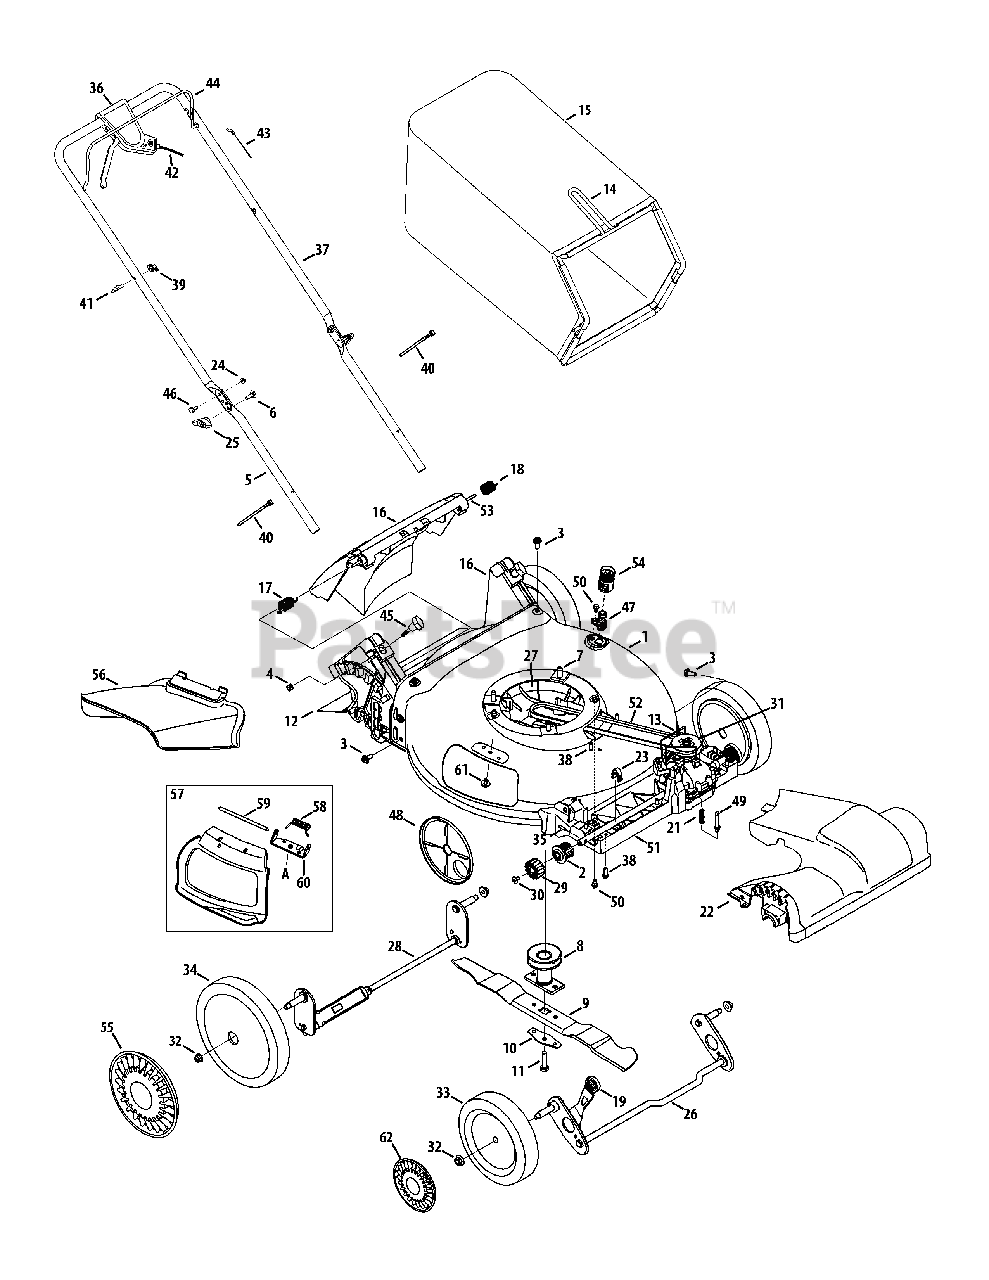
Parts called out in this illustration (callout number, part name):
1	21" Deck Ass’y (w/ side dis. w/nozzle)
2	Bearing Assembly
3	Hex Hd. Cap Screw 5/16-14 x .75
4	Sq. Nut 1/4-20
5	Lower Handle
6	Car riage Bolt 5/16-18
7	Hex Wash HD Tap Scr 3/8-16 x 1.0
8	Blade Adapter
9	21" Mulching Blade
10	Blade Bell Support
11	Hex Bolt 3/8-24 x 1.5" Lg. (Gr 8)
12	Trailing Shield 4.54 x 17.37
13	Wire
15	Grassbag, Black Dust Block ing
16	Rear Baf fle Ass'y (Incl. door)
17	RH Torsion Spring
18	LH Torsion Spring
20	Sems TT Screw 1/4-20 x .50
21	Compression Spring 1.320
22	Front Axle Cover
23	Axle Clip
24	Flanged Lock Nut 1/4-20 Gr. F Ny lon
25	Wing Knob
26	Front Axle Ass'y - 8 " wheel
27	Engine Baf fle Ass'y
28	Rear Axle Ass'y - 8" wheel
29	Spur Gear 14 T LH
29	Spur Gear 14 T RH
30	Screw 1/4-20 x .390
31	Transmission Ass'y
32	Flange Locknut 3/8-16 Gr. F Ny lon
33	Front Wheel
34	Rear Wheel
35	Dowel Pin 3/16 x 3/4
36	Control Lever Ass'y
37	Upper Handle - Black
38	Screw, 1/4-15 x .750
39	Knob 1/4-20
40	Cable Tie
41	Rope Guide Bolt
42	Drive Cable
43	Control Cable
45	Knob 1/4-20 x 1.73 Black
46	Shoulder Screw .375 x .126 x 1/4-20
47	Deck Water Nozzle
48	Dust Cover
49	Compression Spring Body
50	Shoulder Screw 1/4-20 x .50
51	Front SP Tray
52	V Belt
53	Pivot Rod
54	Water Nozzle Adapter
55	Hub Cap (11")
56	Chute Deflector
57	Mulching Plug Ass'y (Incl. ref. no. 58-60)
58	Torsion Spring
59	Hinge Pin
60	Chute Deflector Bracket
61	Screw 1/4-20 x .50
62	Hub Cap
